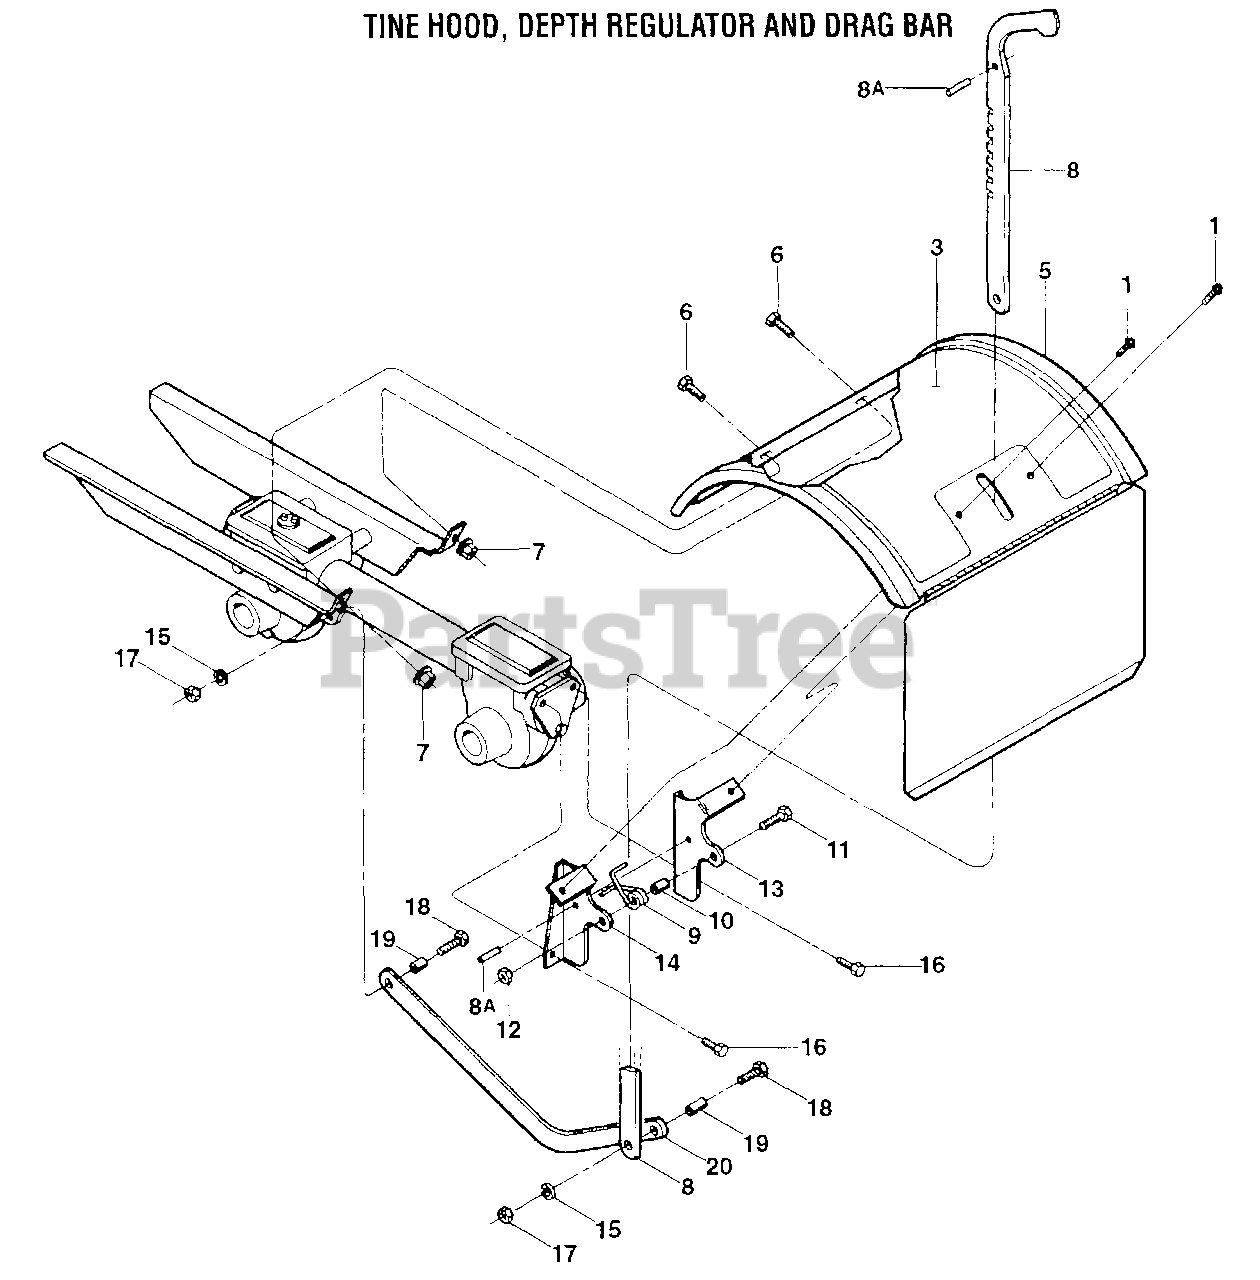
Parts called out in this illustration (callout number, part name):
1	Flange Screw, Self-Tapping, 1/4-20 x 1/2
3	Decal, Hood
5	Tine Hood
6	Hex Screw, 5/16-18 x 1/2
7	Flange Lock Nut, 5/16-18
8	Depth Regulator Lever
8A	Spirol Pin
9	Spring, Depth Regulator
10	Spacer
11	Hex Screw, 1/4-20 x 1
12	Locknut, 1/4-20
13	Hood Bracket, Right Hand
14	Hood Bracket, Left Hand
15	Lockwasher, 5/16
16	Flange Screw, 5/16-18 x 1
17	Hex Nut, 5/16-18
18	Hex Hd. Screw, 5/16-18 x 1-1/4
19	Bushing
20	Drag Bar
